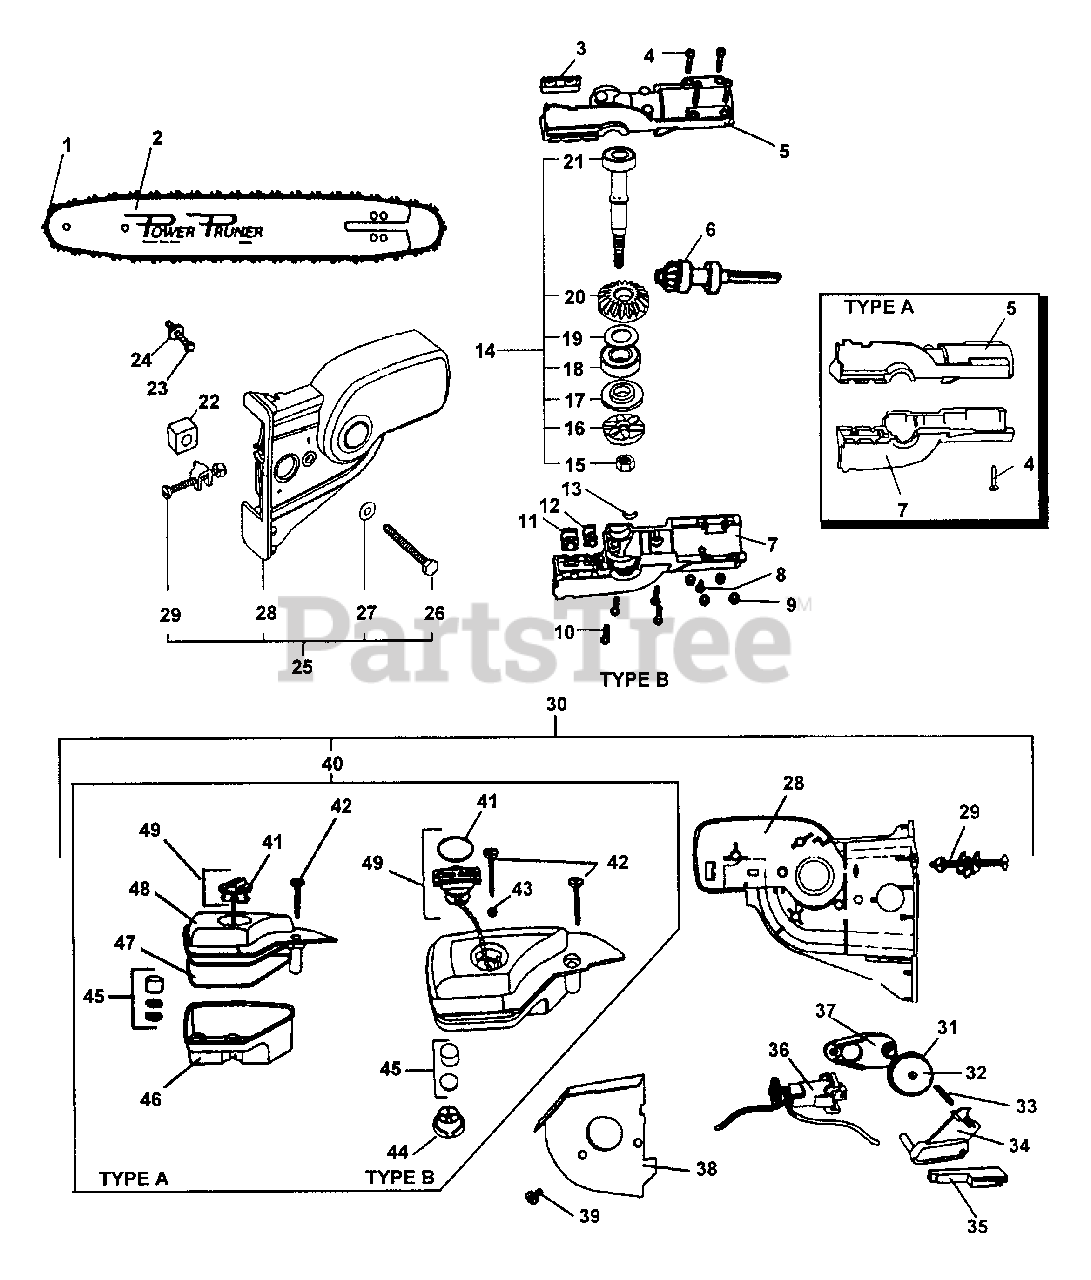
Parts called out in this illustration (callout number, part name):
1	SAW CHAIN - 10" (25cm)
2	GUIDE BAR - 10" (25cm)
3	BRACKET, GUIDE BAR
4	SCREW - 10-24 X 1-1/4"
5	CASE, GEAR - UPPER
6	SHAFT GEAR ASSY
7	CASE, GEAR - LOWER
8	SCREW
9	LOCKNUT - 10-24
10	SCREW - 10-24 X 7/8"
11	SPACER
14	GEAR SHAFT ASSY
16	SPROCKET, DRIVE
17	SPACER, SPROCKET
18	BEARING, BALL - 6001 DDU
20	GEAR - BEVEL
21	DRIVESHAFT SPROCKET ASSY
22	SPACER
23	SCREW - 1/4-20 X 1-3/4"
25	OILER COVER ASSY
26	BOLT - 1/4-20 X 2-1/4"
28	COVER, OIL PUMP
29	TENSIONER KIT
30	AUTO-OILER ASSY
32	CAM, OIL PUMP
34	LINK, OILER IDLER
35	PIPE, OIL OUTLET
36	AUTO-OILER ASSY
37	LINK, OILER DRIVE
40	OIL TANK ASSY
42	SCREW - 8-32 X 1"
44	HOUSING, OIL FILTER
45	OIL FILTER ASSY
46	TANK, OIL (BOTT)
47	O-RING
48	TANK, OIL (TOP)
49	CAP ASSY
